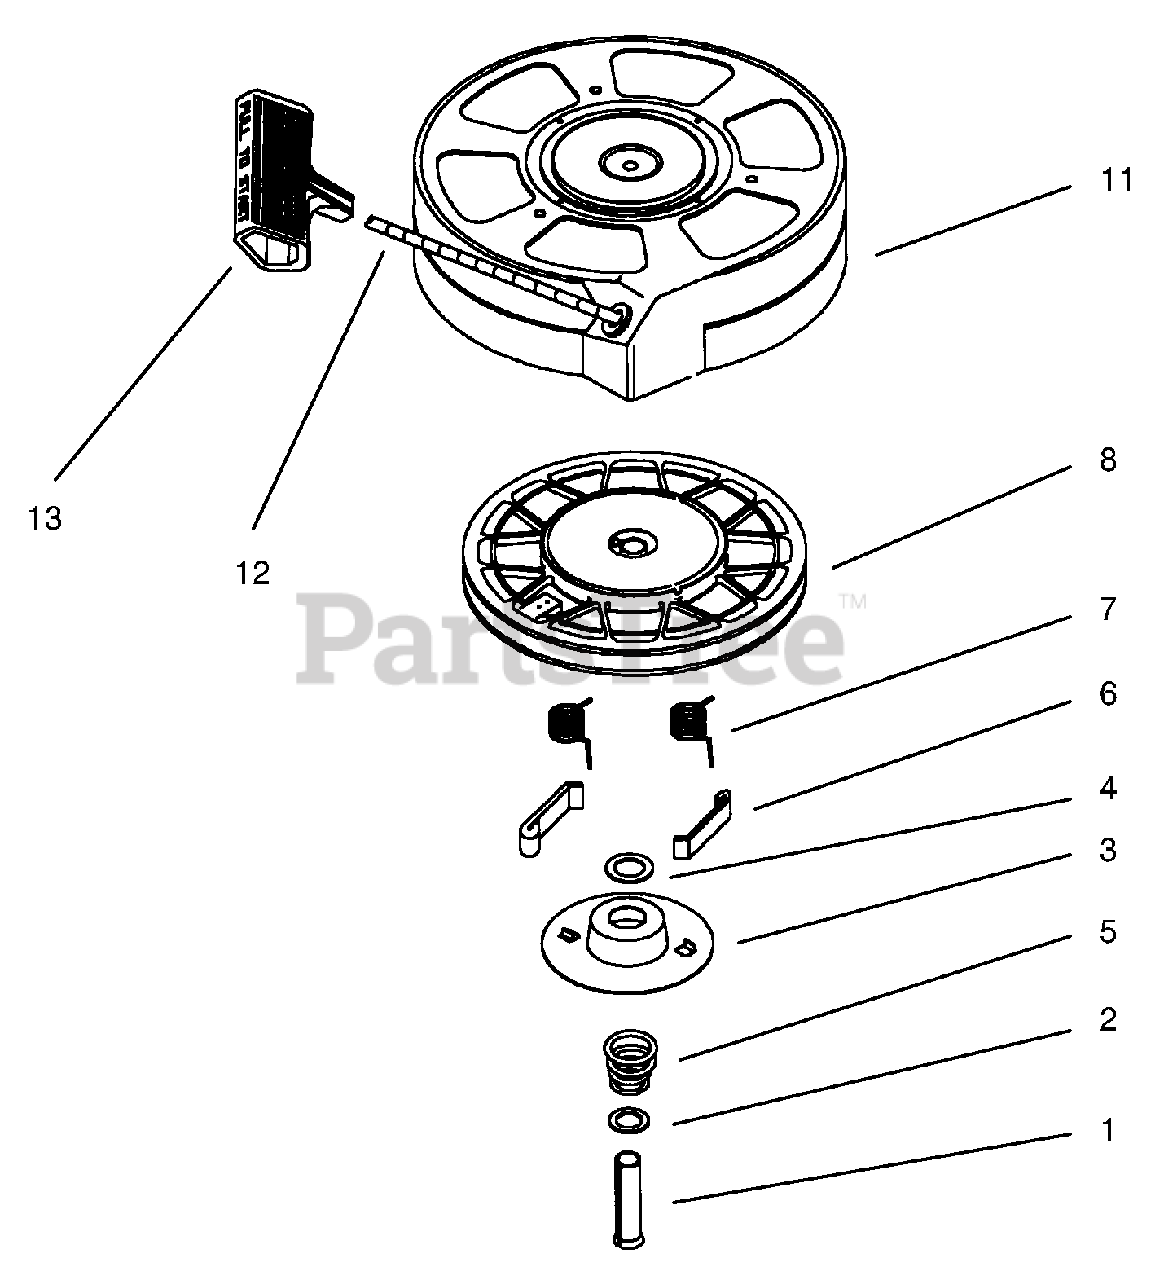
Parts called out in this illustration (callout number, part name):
1	Spring Pin (Incl. 4)
3	Retainer
5	Brake Spring
6	Starter Dog
7	Dog Spring
8	Pulley & Rewind Spring ASM
11	Starter Housing ASM (40 degree grommet)
12	Starter Rope ( 98" X 9/64" dia.)
13	Starter Handle
